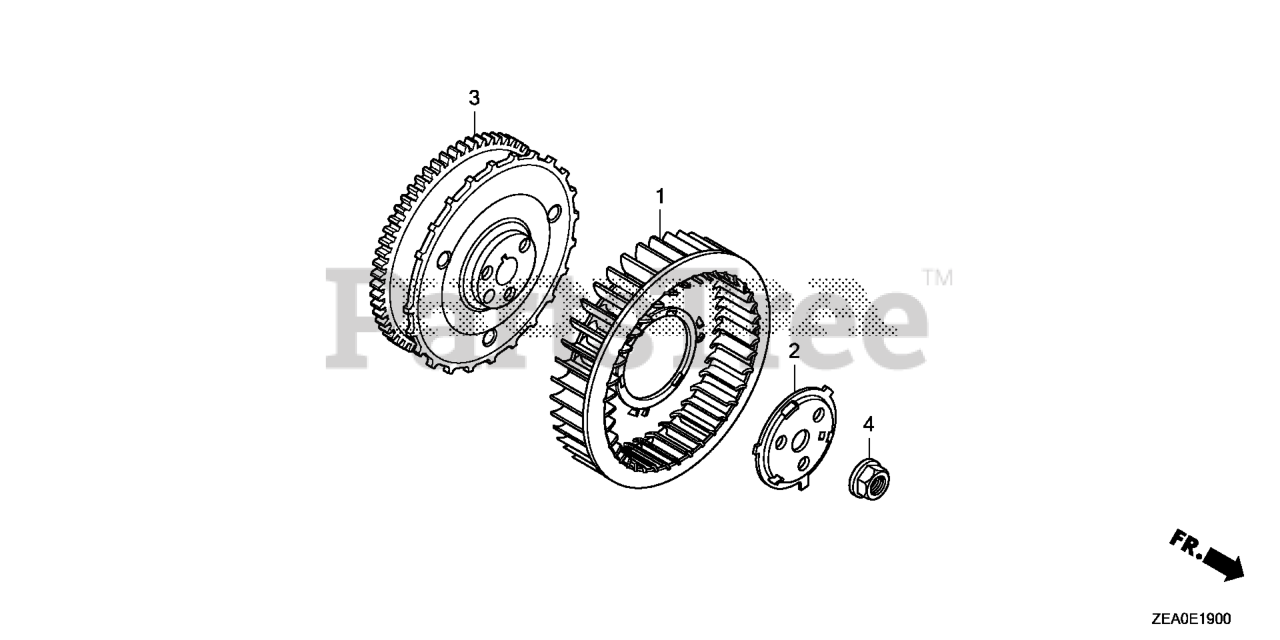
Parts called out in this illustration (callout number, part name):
1	FAN, COOLING
2	PLATE, COOLING FAN SETTING
4	NUT, SPECIAL (20MM)
